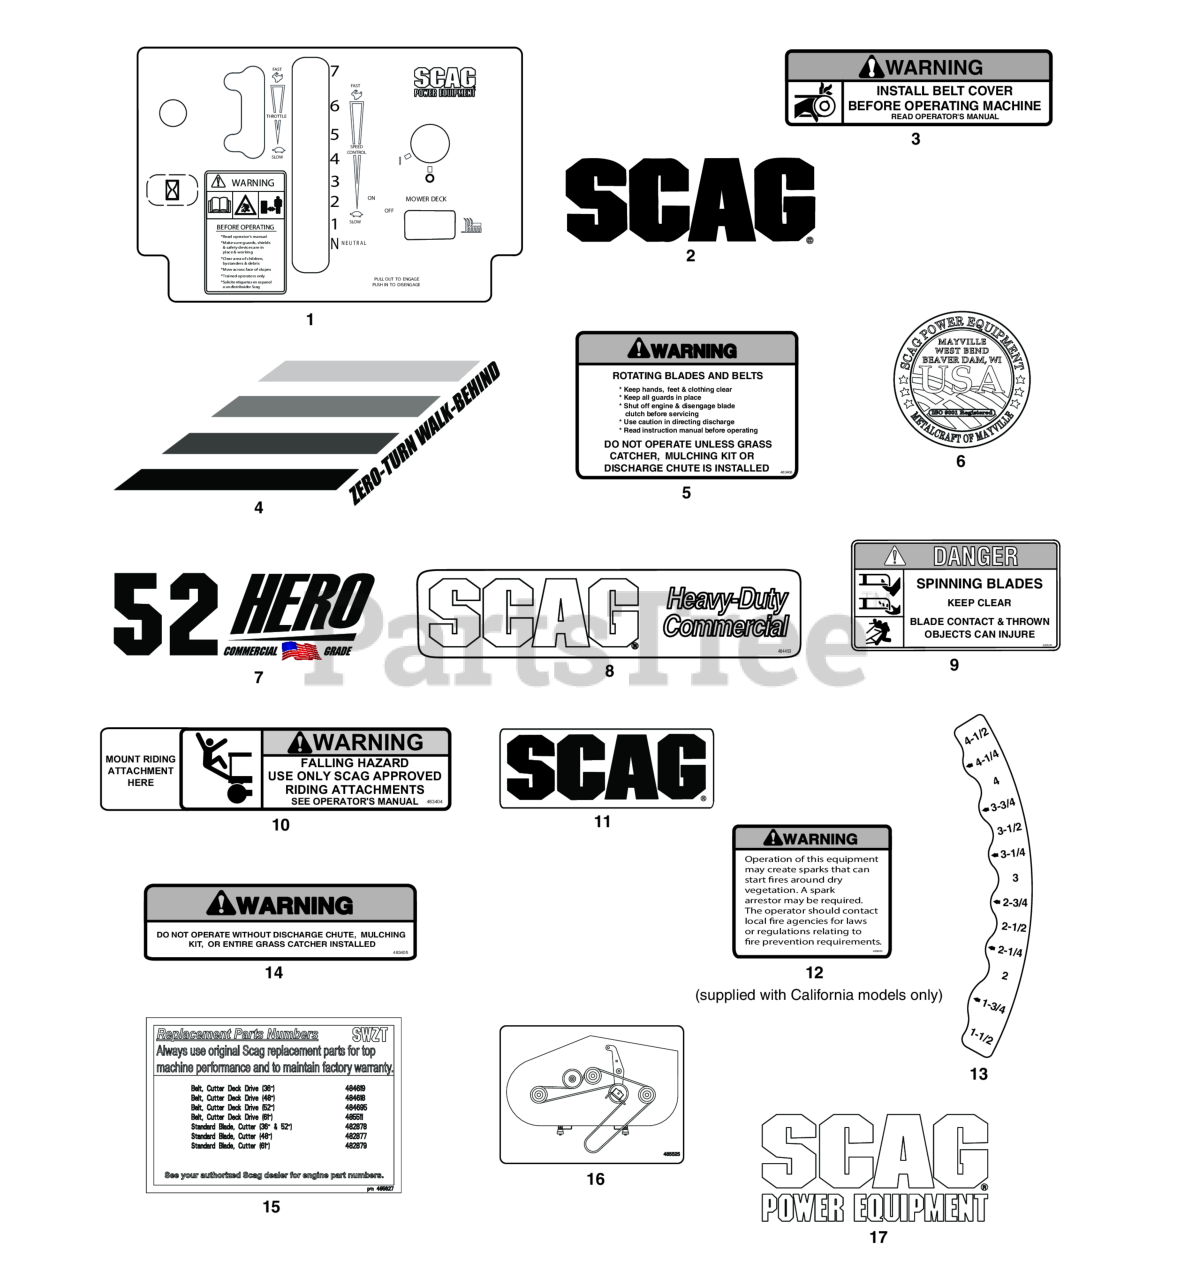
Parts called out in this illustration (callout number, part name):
1	Decal, Instrument Panel (Manual Start)
2	Decal, Scag Logo ( Cutter Deck)
3	Decal, Warning - Belt Cover
4	Decal, Handle - LH
5	Decal, Warning - Rotating Blades
6	Decal, Metalcraft - USA
7	Decal, 48H Commercial
8	Decal, Scag Heavy Duty Commercial
9	Decal, Spinning Blades
10	Decal, Sulky Attachment
11	Decal, Scag Logo
13	Decal, Height of Cut
14	Decal, Warning-Discharge
15	Decal, SWZT Replacement Parts
16	Decal, Belt Routing
17	Decal, Scag Power Equipment (Fuel Tank)
